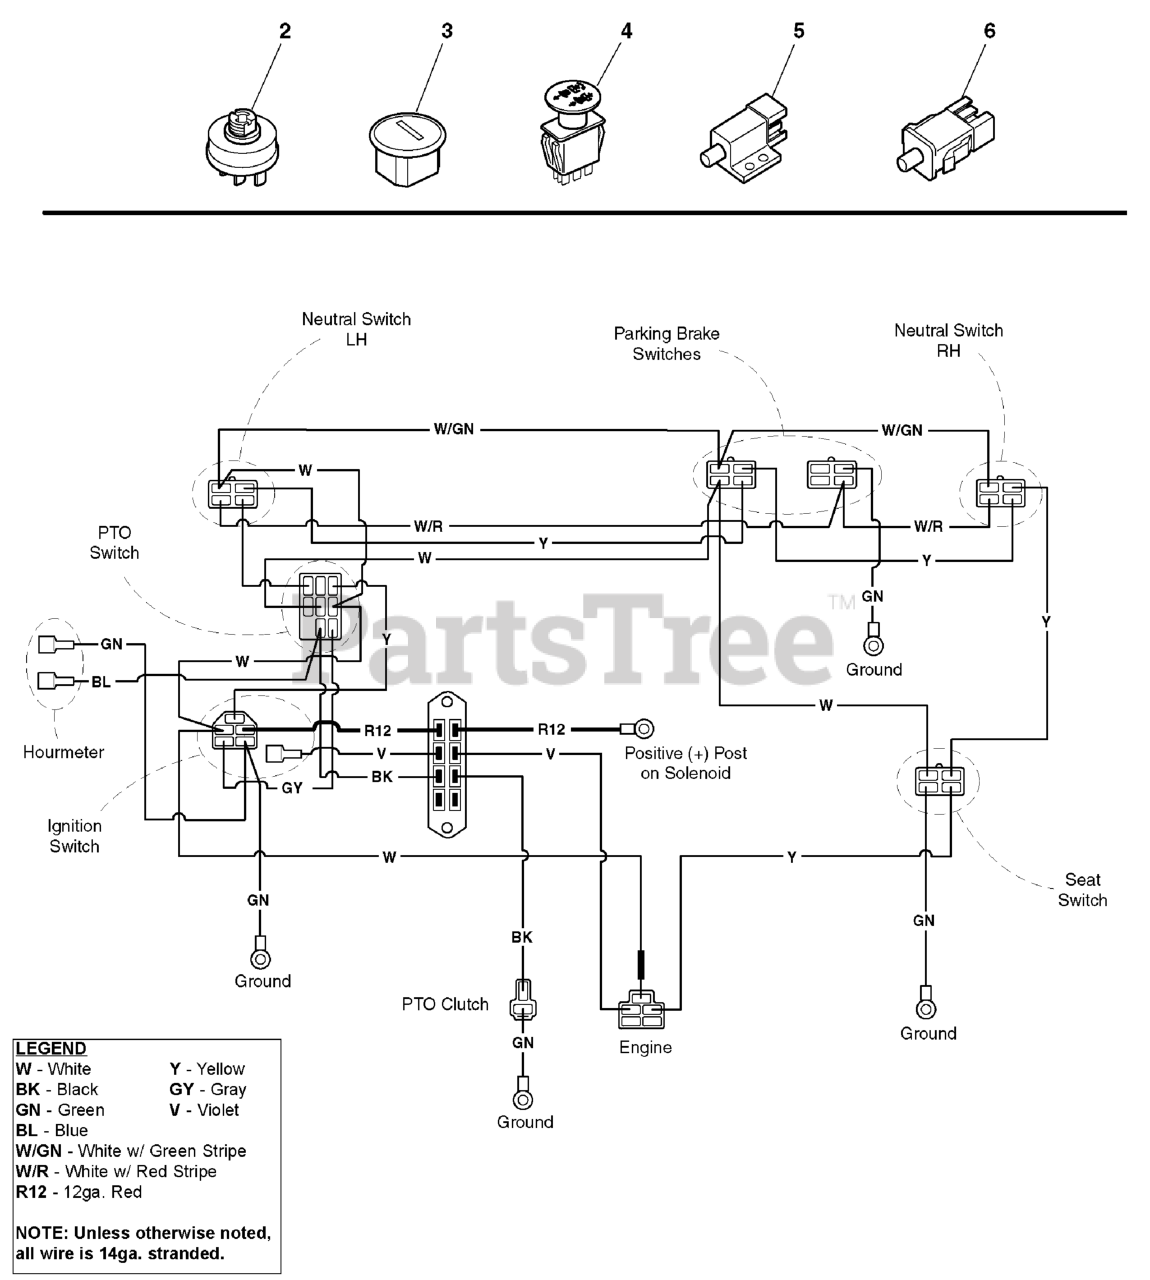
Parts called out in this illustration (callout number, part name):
1	ISZ25K Wire Harness
2	SWITCH, IGNITION, 6 POST
3	HOUR METER
4	SWITCH, BLADE ENGAGEMENT
5	SWITCH, PLUNGER, N.O./N.C.
6	SWITCH, DP NO/NC SNAP-IN
7	BATTERY CABLE, NEG, 22, 1/4-5/16
